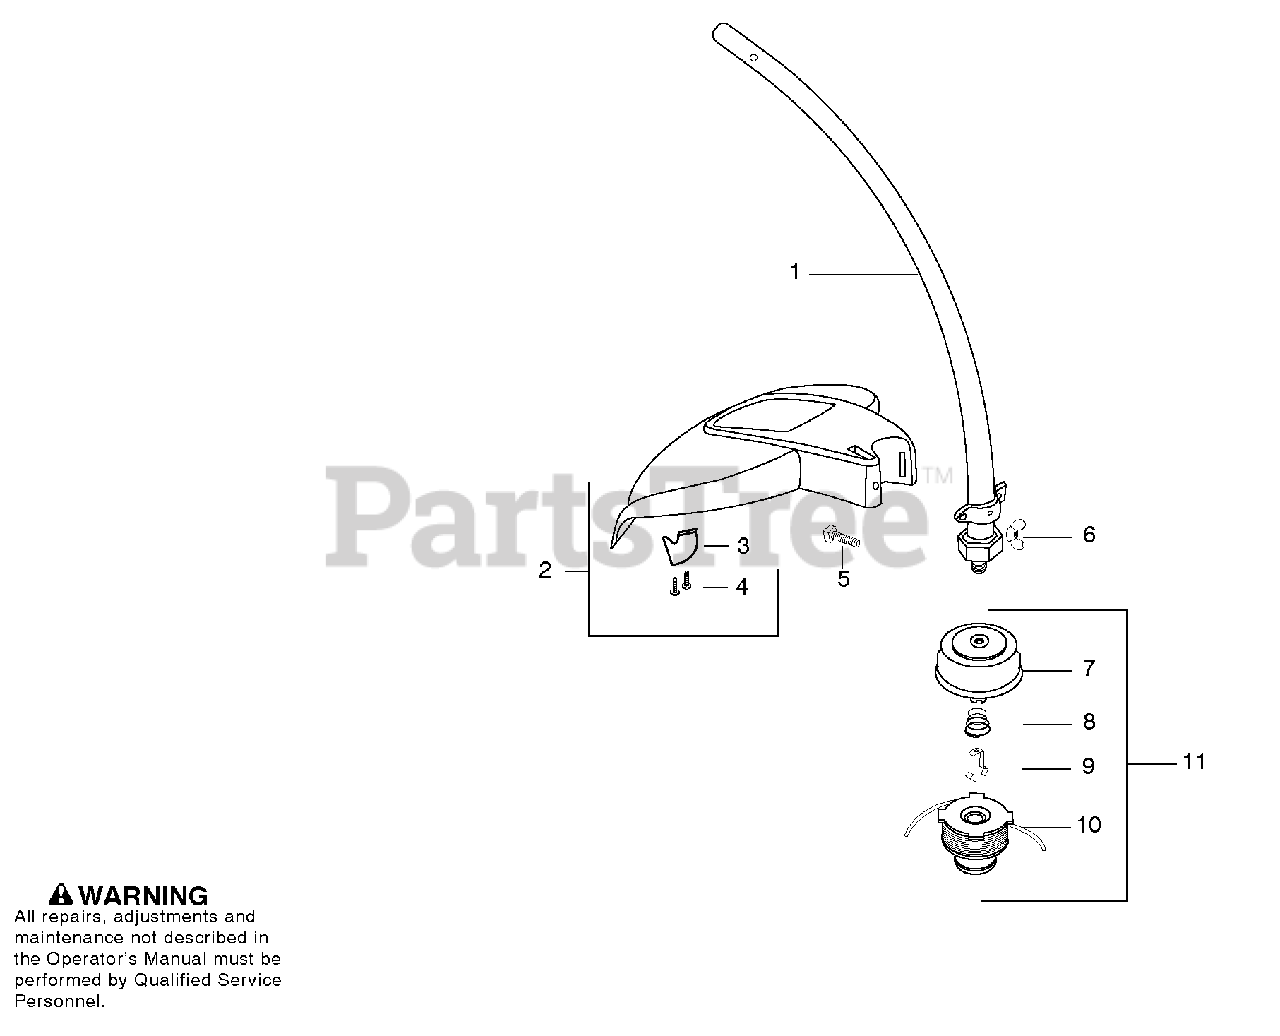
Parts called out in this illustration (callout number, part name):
1	Kit - Lower Shaft Assy.
2	Kit - Shield Assy.
3	Limiter - Line
6	Wingnut
7	Assy - Hub w/arbor
8	Spring - Return
9	Retainer - Spool
10	Accy. - Wound Spool
11	Accy. - Cutting Head Assembly
